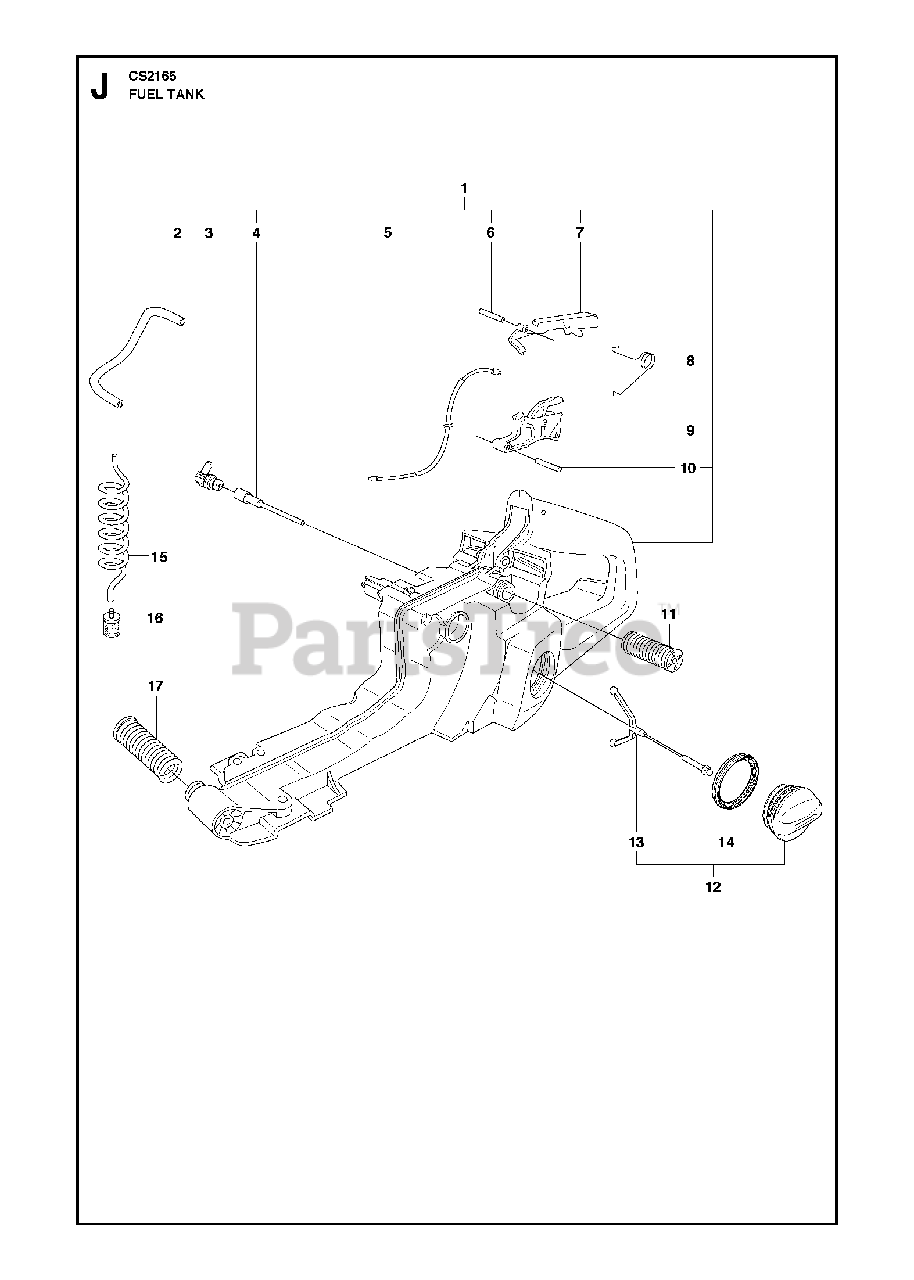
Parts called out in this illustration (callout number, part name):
1	TANK
2	HOSE
3	CONNECTOR
4	TANK VALVE
5	WIRE
6	PIN 3X25
7	THROTTLE LOCK
8	SPRING
9	THROTTLE TRIGGER
10	PIN CPH8 4X20
11	ANTIVIBE MOUNT
12	TANK CAP
13	HOLDER
14	SEALING
15	FUEL HOSE
16	FUEL FILTER
17	ANTIVIBE MOUNT
17	AV SPRING (HARD)
